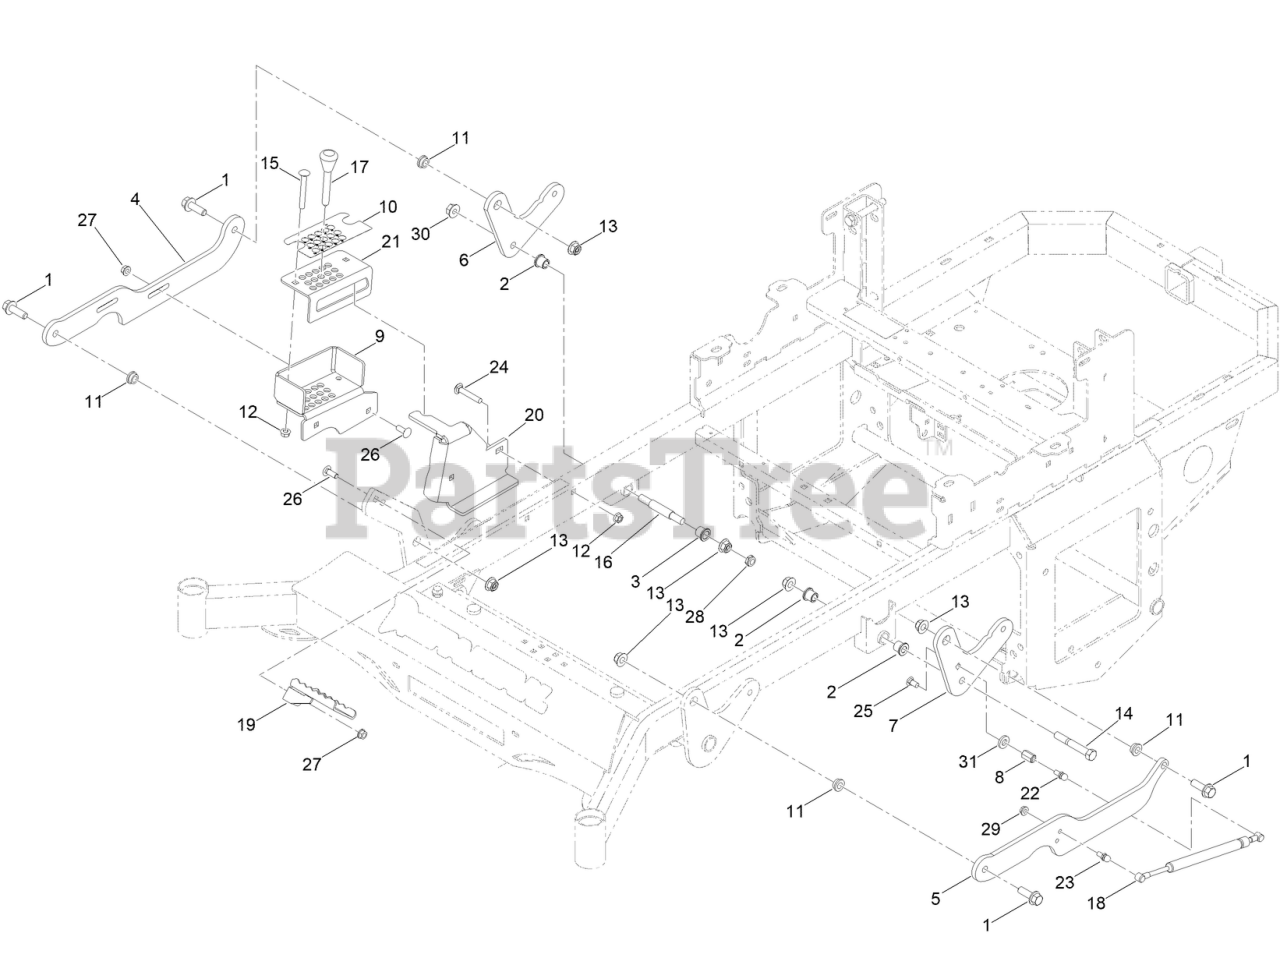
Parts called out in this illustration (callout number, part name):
1	SCREW-HHF
2	BUSHING-FLANGE
3	BUSHING-FLANGE
4	2024 DECK HEIGHT ARM RT LINK
5	LINK-DECKLIFT
6	ARM-DECKLIFT REAR (3/8")
7	ARM-DECKLIFT REAR (3/8")
8	HEX COUPLING NUT - REDUCER (3/8" TO 5/16
9	BRACKET PIN SYSTEM (BOTTOM) PAINTED GREY
10	DECAL-HEIGHT OF CUT
11	1/2IN ID X 3/4IN OD X 3/8IN FLANGE BUSH
13	1/2-13 HEX FLANGE 2-WAY REV CNTR L/NYZ
14	1/2-13 X 3-1/2 HEX C/S GR 5 ZINC YELLOW
15	(3/8-16 X 3 CARRIAGE BOLT (GR.5) ZC/YEL)
16	RR DECK HEIGHT BOLT (MACHINED)
17	MAGNETIC PIN FOR STAND ON MWR
18	DECK ASSIST GAS SPRING
19	MWR DECK HEIGHT FOOT PEDAL PAINT
20	2022 DECK LOCK PIN TUBE BRKT
21	2022 DHI PIN ARM LINK TOP BRKT
22	5/16-18X1.286 DAMPER BALL STUD (.562 TL)
23	5/16-18X1.286 DAMPER BALL STUD (.562 TL)
24	SCREW-CARR
25	3/8 X 3/4IN GR 8 CARR BOLT ZINC
26	3/8-16 X 1 CARRIAGE BOLT YZ GR.8
27	3/8-16 HEX FLANGE NUT W/SERR ZINC YELLOW
28	NUT-HEX
30	NUT-HHF
31	5/16IN USS FLAT WASHER (3/8 ID X 7/8 OD)
